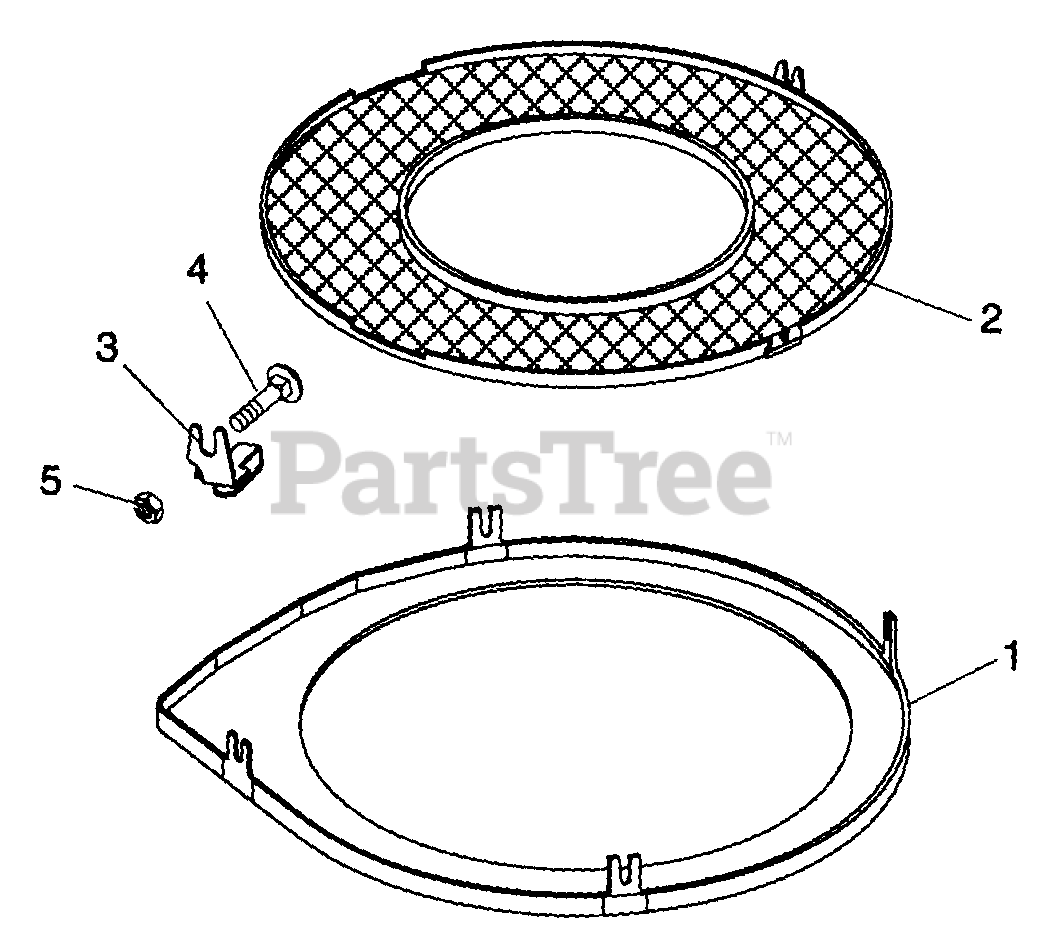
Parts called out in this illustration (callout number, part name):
1	BOTTOM PLATE
2	SCREEN WELDMENT
3	SCREEN MOUNT LONG
4	BLT-RDHDSQNK .31-18X1.00 PL
5	NUT-FLG. .312-18 PL
